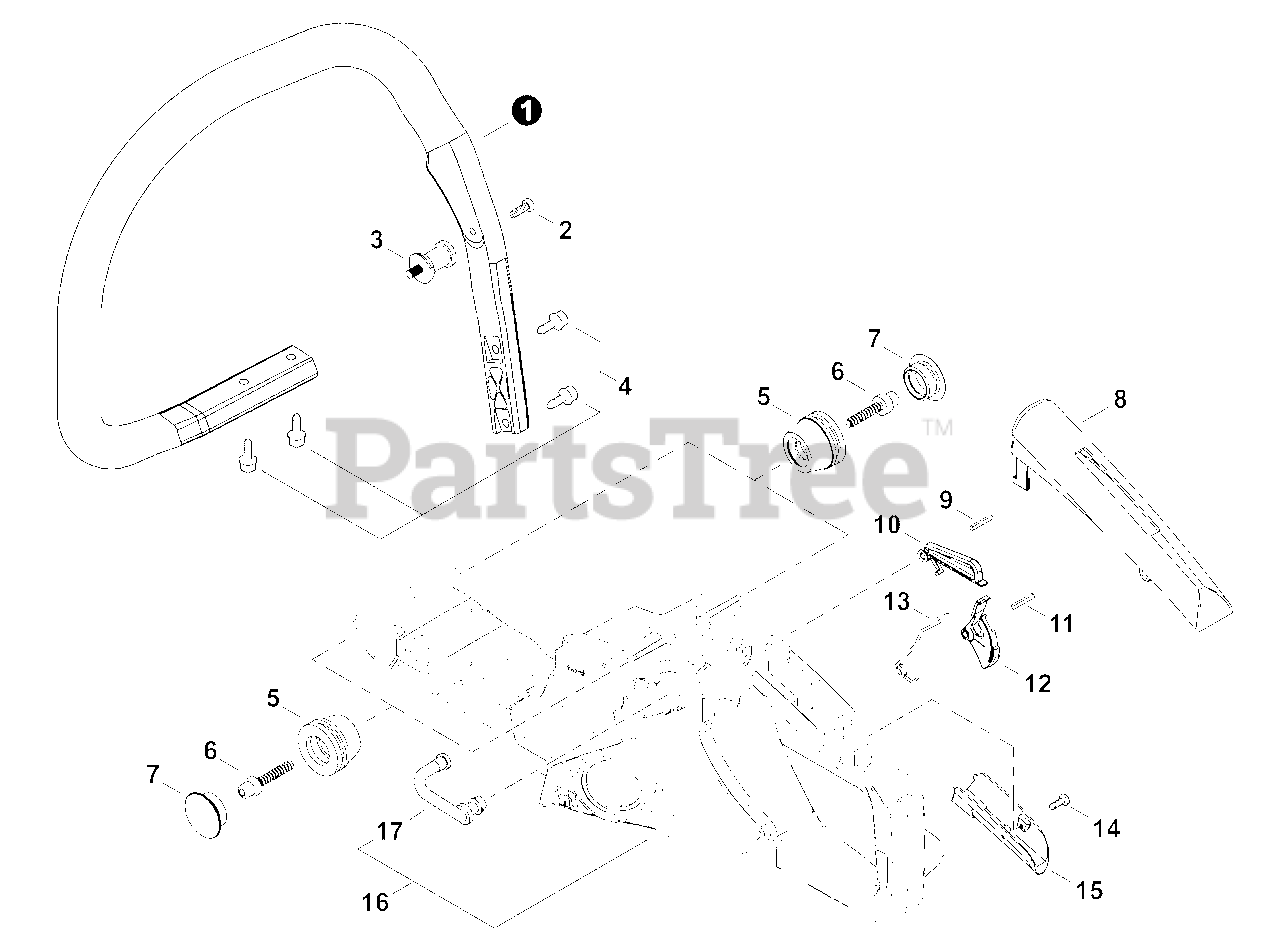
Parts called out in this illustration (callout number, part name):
1	HANDLE, FRONT
2	BOLT M4×14
3	CUSHION 5
4	BOLT 5×20
5	CUSHION
7	CAP, CUSHION
8	COVER, HANDLE
9	LOCKOUT, THROTTLE
10	PIN, SPRING Ø4×25 MM
11	PIN, SPRING Ø4×22 MM
12	TRIGGER, THROTTLE
13	SPRING, THROTTLE RETURN
14	SCREW 4×25
15	GRIP, HANDLE
16	HANDLE ASSY, REAR
17	PIPE, FUEL VENT
